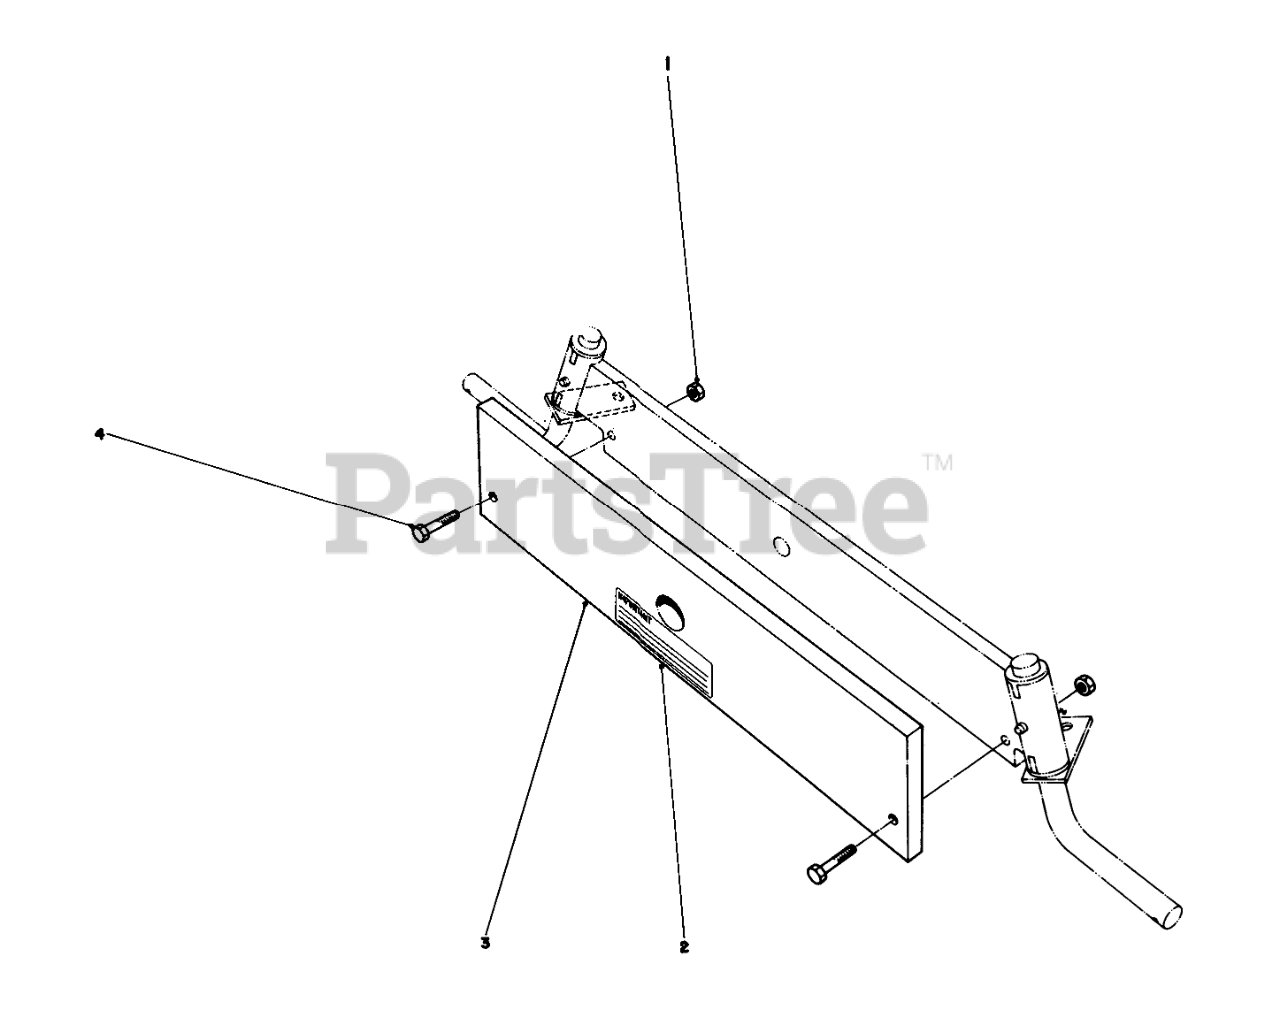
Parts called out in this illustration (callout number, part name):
2	Decal-Warning
3	Counterweight (Incl. Ref. #2)
4	SCREW-HH
